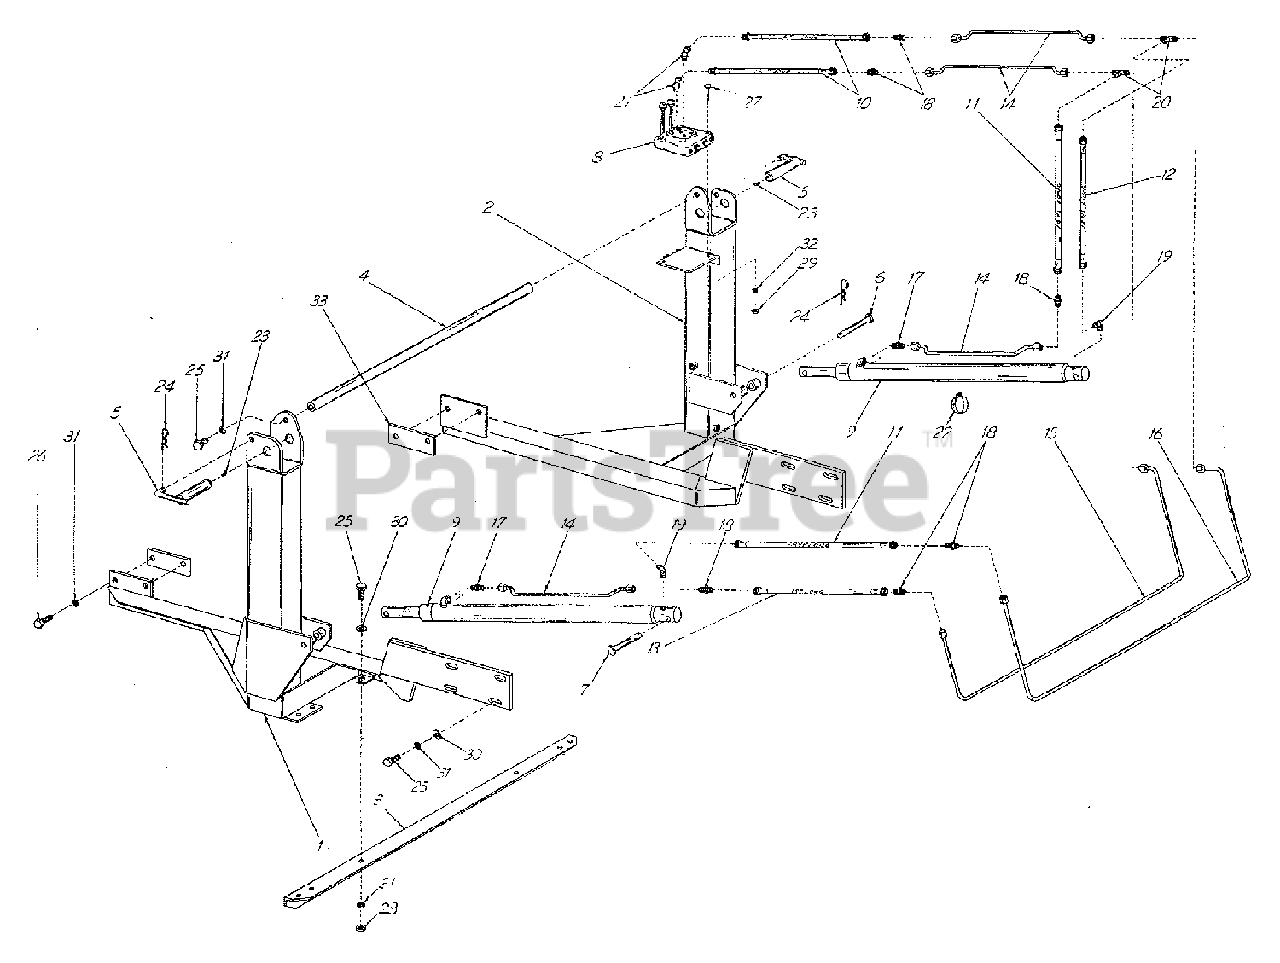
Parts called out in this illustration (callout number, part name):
1	SIDE FRAME RH WELDED ASSEMBLY
2	SIDE FRAME LH WELDED ASSEMBLY (Reservoir)
3	BOTTOM SUPPORT ANGLE
4	BAR, Support
5	PIN, Lock
8	HYDRAULIC VALVE
9	HYDRAULIC CYLINDER
10	HYDRAULIC HOSE, 1/4 ID x 16-1/2" Long
11	HYDRAULIC HOSE, 1/4 ID x 18-1/2" Long
12	HYDRAULIC HOSE, 1/4 ID x 13-1/2" Long
13	HYDRAULIC HOSE, 1/4 ID x 15 " Long
14	HYDRAULIC TUBE ASSEMBLY
15	HYDRAULIC TUBE ASSEMBLY
16	HYDRAULIC TUBE ASSEMBLY
17	STRAIGHT ADAPTER
18	STRAIGHT ADAPTER
19	ELBOW ADAPTER, 90 Degrees
20	UNION TEE
21	UNION ADAPTER, 45 Degrees
22	HOSE CLAMP
23	FITTING, Grease, 45 Degrees
24	PIN, Hair, #3
25	BOLT, 1/2 NC x 1-1/4 Hex Head Capscrew
26	BOLT, 1/2 NC x 2" Hex Head Capscrew
27	BOLT, 1/4 NC x 2" Hex head Capscrew
28	NUT, 1/2 NC Hex
29	NUT, 1/4 NC Hex
30	WASHER, 1/2 Plain Standard
31	WASHER, 1/2 Lock
32	WASHER, 1/4 Lock
33	REAR SPACER PLATE
